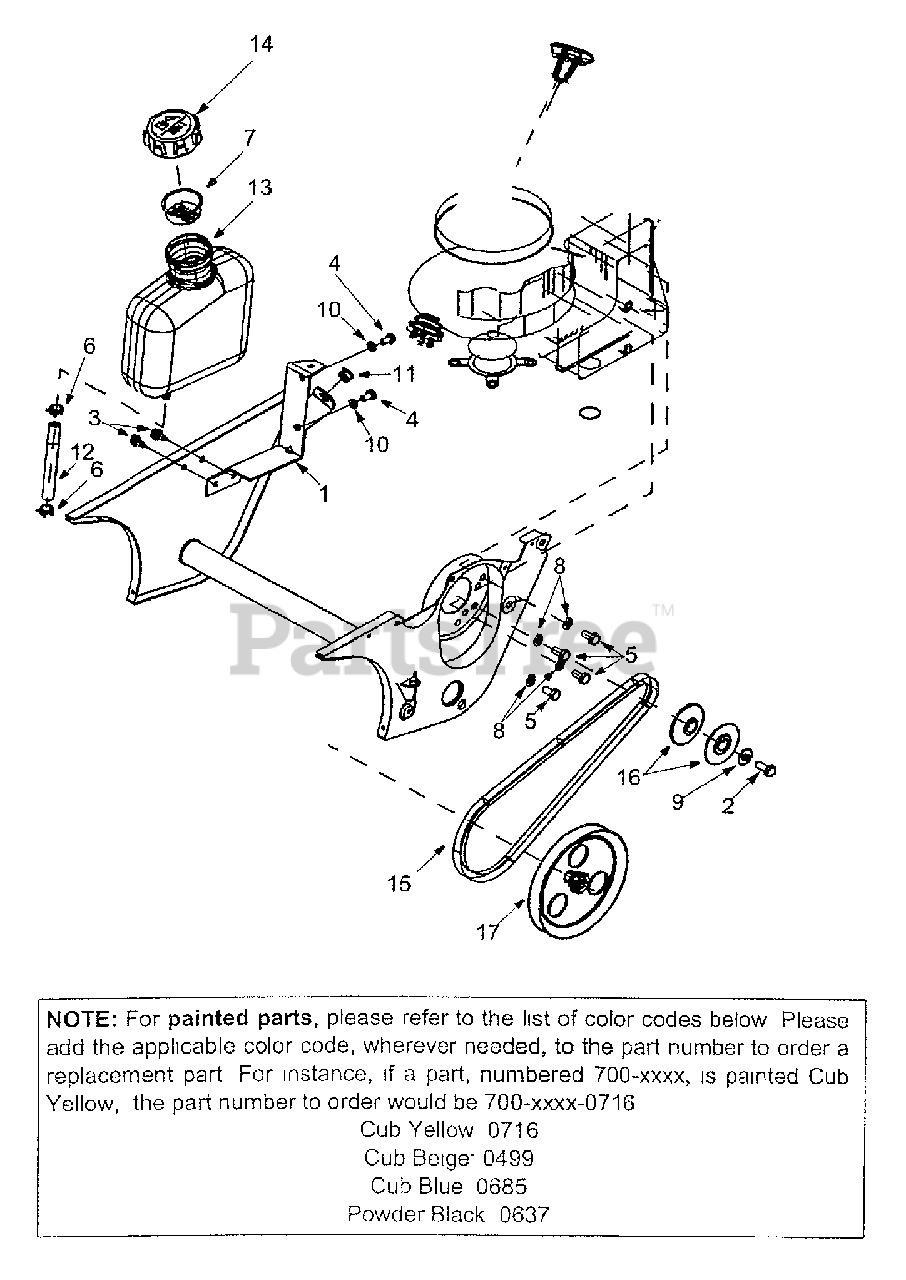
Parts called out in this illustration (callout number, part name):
3	Self-Tapping Screw
4	Hex Screw 1/4-20 x .50"
5	Hex Screw
6	Hose Clamp
8	Lock Washer
9	Beleville Washer
10	Lock Washer
11	Plastic Bushing
12	Fuel Line Hose
13	Fuel Tank: 2 Quart
14	Fuel Cap
15	V-Belt
16	V-Pulley Half
17	V-Pulley Half
